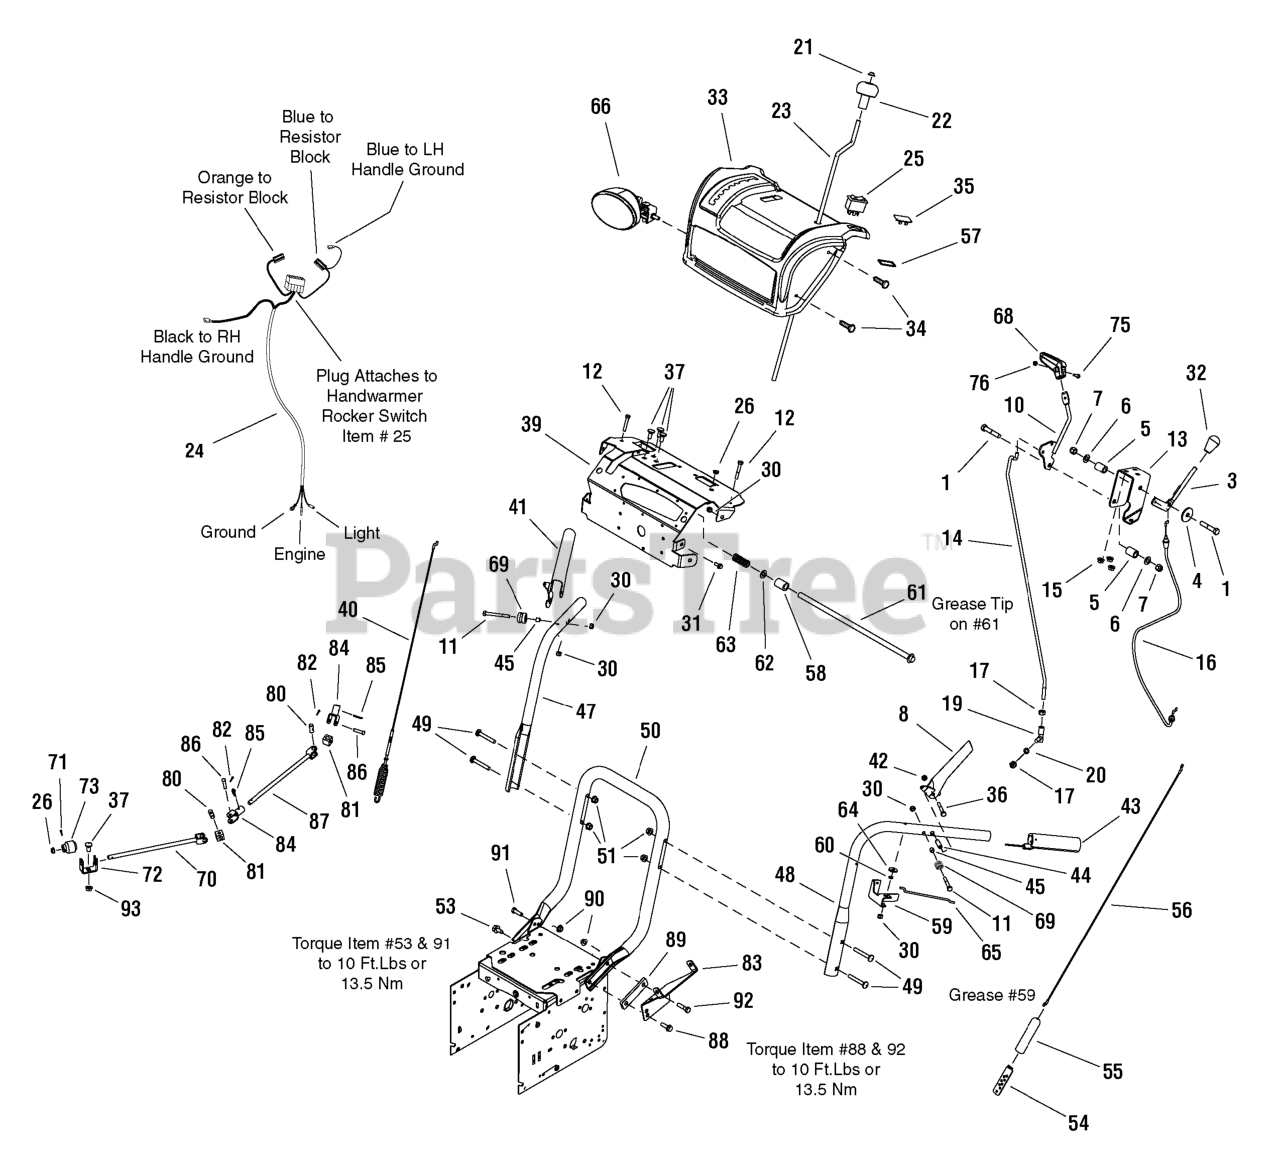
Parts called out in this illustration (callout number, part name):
1	CAPSCREW, Hex Head 3/8-16 x 2 G5
3	ROD, Remote Chute
4	WASHER, 3/8
5	SPRING, Compression .509 DIA x 3/4
6	WASHER, 3/8
7	NUT, Hex Lock ESNA Light 3/8-16 NC3B
8	HANDLE, Clutch L.H.
10	ROD & PLATE ASSEMBLY, Speed Control
11	CAPSCREW, Hex Head 1/4-20 x 2-1/2 G5
12	CAPSCREW, Hex Head 1/4-20 x 1-3/4 G5
13	BRACKET, Speed & Deflector Control 12GA
14	ROD, Link Speed Control
15	NUT, Hex Flange 5/16-18, Whiz Lock Small
16	CABLE, Deflector Control
17	NUT, Hex 5/16-24
19	BALLJOINT, Steel
20	LOCKWASHER, Spring 5/16
21	NUT, Push Pal 5/16 Diameter Stud Capped
22	KNOB, Spinner
23	ROD, Chute Control
24	HARNESS, Wiring, Handwarmers
25	SWITCH, Handwarmers
30	NUT, Hex Lock ESNA Light 1/4-20
31	SCREW, Hex Washer Head Taptite 1/4-20 x 5/8
32	KNOB, Interior Thread 3/8-16
33	COVER, Panel 16GA
34	SCREW, Truss Head Torx Drive 1/4-20 x 3/4
35	PLUG, Dash Hole
36	CAPSCREW, Hex Head 1/4-20 x 1-1/2 G5
37	CARRIAGE BOLT, 5/16-18 x 3/4 G5
39	SUPPORT, Dash Panel Cover
40	CABLE & SPRING ASSEMBLY, Auger Drive R.H.
41	HANDLE, Clutch R.H.
42	NUT, Hex Centerlock 1/4-20
43	GRIP, Black Soft 1" Diameter
44	SPACER, Handle
45	SPACER
47	HANDLE, Upper R.H. Tubular
48	HANDLE, Upper L.H. Tubular
49	CARRIAGE BOLT, 5/16-18 x 2-1/4 G5
50	HANDLE, Lower Tubular
51	NUT, Hex Flange 5/16-18 ESNA
53	SCREW, Hex Washer Head Taptite 5/16-18 x 3/4
54	BRACKET, Cable Adjusting 13GA
55	BOOT, Spring End Cover
56	CABLE, Drive
57	SHIM, Spacer 18GA
58	SPACER, 1/2 x 7/8 x 1 3/16
59	BRACKET, Free Hand Control
60	SPACER, Powdered Metal
61	ROD & SPRING ASSEMBLY, w/Pin
62	WASHER, 1/2
63	SPRING, Compression
64	WASHER, 1/4
65	ROD, Hold Down
66	HEADLIGHT ASSEMBLY, Oval Clear
68	KNOB, Slot Speed
69	SPOOL CABLE, Auger Control
70	ROD & YOKE ASSEMBLY, Chute
71	PIN, Spring
72	SUPPORT, Worm 10GA
73	WORM, Chute L.H.
75	SCREW, Round Head Phillips #10-24 x 3/4
76	NUT, Hex Lock 10-24 W/Nylon Insert
80	PIN, Universal Joint
81	BLOCK, Universal Pivot
82	PIN, Cotter
83	SUPPORT, Chute Rod
84	YOKE & TUBE ASSEMBLY, Chute
85	PIN, Hair Chute Gear
86	PIN, Clevis
87	ROD & YOKE ASSEMBLY, Chute
88	SCREW, Hex Washer Head Taptite 5/16-18 x 1
89	SPACER, Block
90	NUT, Hex Flange 5/16-18 Two-Way Lock
91	CAPSCREW, Hex Head, 5/16-18 x 1
92	CAPSCREW, Hex Head, 5/16-18 x 1 1/4
93	NUT, Hex KEPS 5/16-18 Conical Washer
